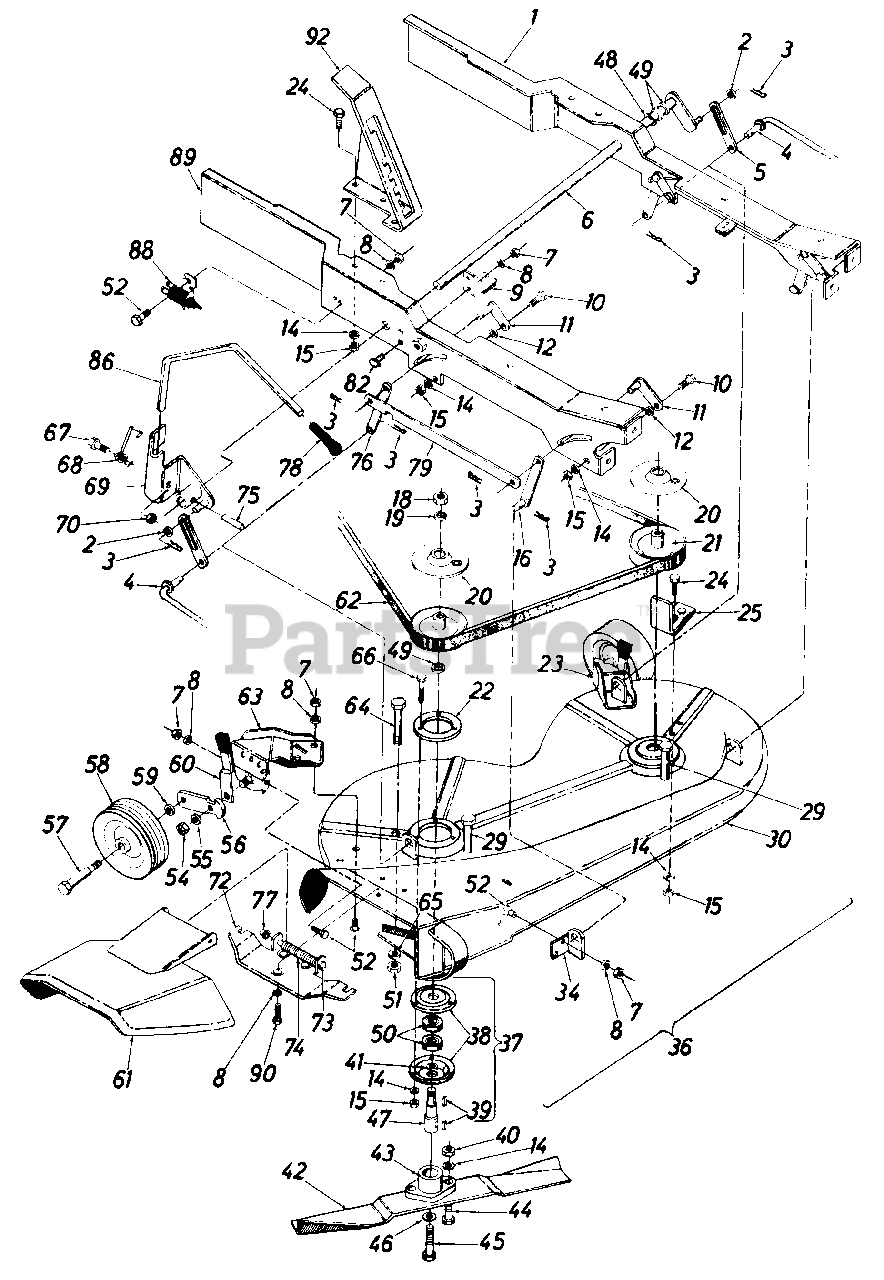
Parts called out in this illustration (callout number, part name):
1	Side Rail Ass'y. - L.H.
2	Flat Washer .531 I.D. x .930 O.D. x .090
3	Internal Cotter Pin for 1/2" Dia.
4	Stabilizer Rod
5	Slotted Link
6	Lift Shaft Ass'y.
7	Hex Nut 1/4-20 Thd.
8	Spring Lock Washer 1/2" Scr.
9	Blade Brake Ass'y.
10	Shld. Scr. .437" Dia. x .180
11	Pivot Link Ass'y.
12	Flat Washer .344 I.D. x .62" O.D.
14	Spring Lock Washer 5/16"
15	Hex Nut 5/16-18 Thd.
16	Deck Link Ass'y.
18	Hex Jam L-Nut 5/8-11 Thd.
19	Spring Lock Washer 5/8" Scr.
20	Brake Disc Ass'y.
21	Deck Pulley
22	Reinforcement Plate
23	Wheel Bracket Ass'y. - L.H.
24	Hex Scr. 5/16-18 x .75"
25	Belt Keeper Ass'y.
29	Shld. Scr. .498" Dia. x 2.00"
30	Deck Ass'y.
34	Deck Bracket
36	34 Inch Deck Ass'y. - Comp.
37	Blade Spindle Ass'y. - Comp.
38	Bearing Cup
39	#6 Hi-Pro-Key 5/32 x 5/8"
40	Hex Nut 5/16-24 Thd.
41	Fl-Wash. .793 I.D. x 1.24 O.D.
42	17 Inch Blade
43	Blade Adapter Kit
44	Hex Scr. 5/16-24 x 1.00" Lg.
45	Hex Scr. 3/8-24 x 1.50" Lg.
46	Spring Lock Washer 3/8" Scr.
47	Blade Spindle
48	Wave Washer .62" I.D.
49	Flat Washer .635 I.D. x 1.135
50	Ball Bearing
51	Hex Nut 3/8-16 Thd.
52	Hex Scr. 1/2-20 x .50" Lg.
54	Hex Inserted Lock Nut 3/8-24
55	Belleville Washer .40" I.D. x 1.13 O.D. x .030
56	Wheel Pivot Bar
57	Shld. Scr. 5/8" Dia. x 1.75"
58	5" Wheel Ass'y.
59	Belleville Washer .400 I.D. x .88" O.D. x .060
60	Spring Lever Ass'y. w/knob
61	Chute Cover Ass'y. - Comp.
62	"V"-Belt 21/32 x .82" Lg.
63	Wheel Bracket Ass'y. - R.H.
64	Shld. Scr. .498" Dia. x 1.450" Lg.
65	Spring Lock Washer 3/8" Scr.
66	Hex Scr. 5/16-18 x 1.00" (Grade 5)
67	Hex Scr. 1/4-20 x 1.50" Lg.
68	Torsion Spring
69	Handle Bracket Ass'y.
70	Hex Center Lock Nut 1/4-20
72	Adapter Ass'y.
73	Hinge Pin
74	Torsion Spring
75	Spring Pin 5/16" Dia. x 1.38"
76	Deck Link
77	Push Nut 1/4" Rod
79	Connecting Rod
82	Carriage Bolt 1/4-20 x .62"
86	Lift Handle
88	Safety Switch (Lift)
89	Side Rail Ass'y. - R.H.
90	Hex Scr. 1/4-28 x .62" Lg.
92	Index Bracket
